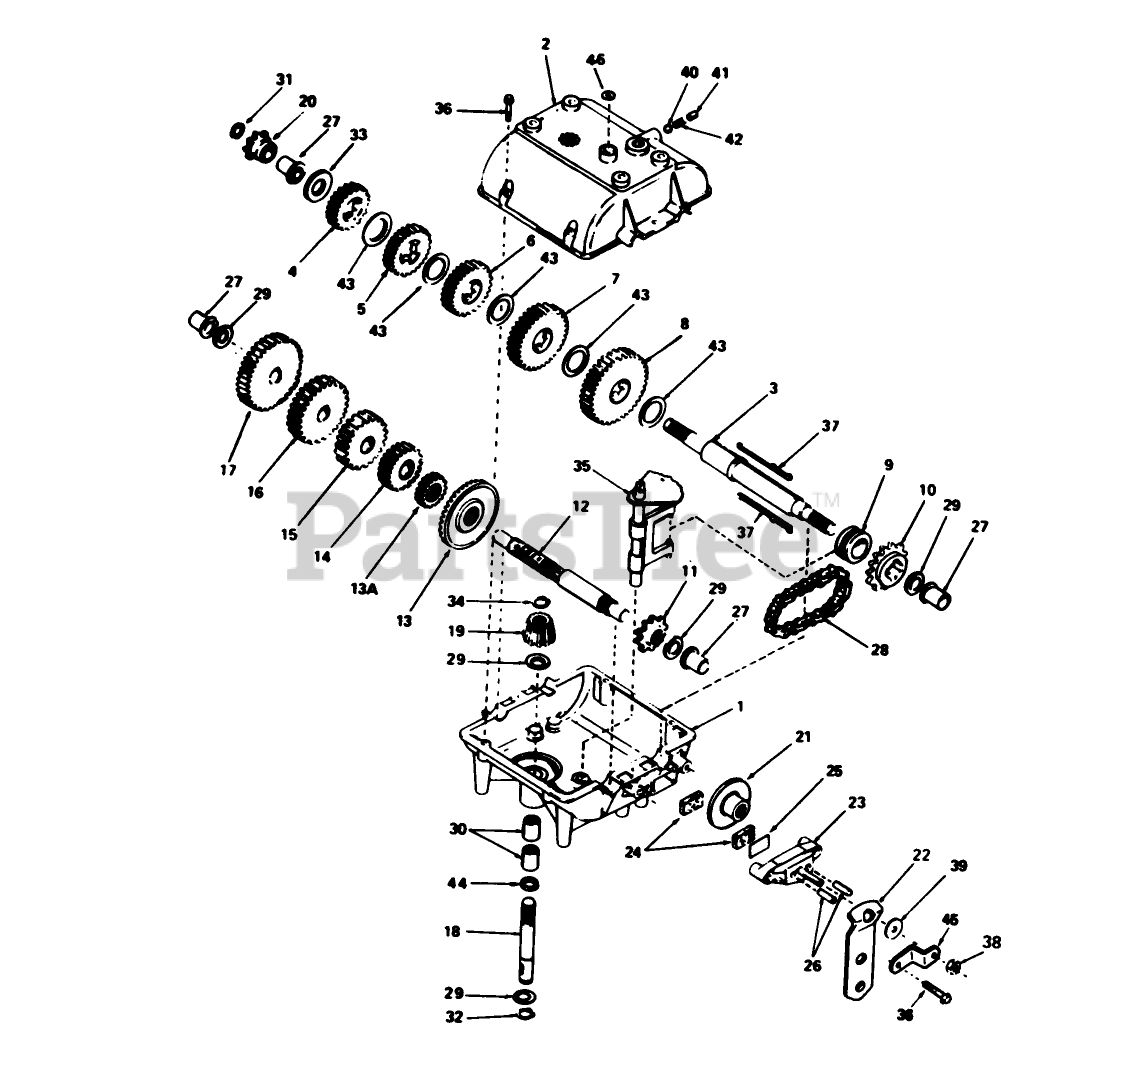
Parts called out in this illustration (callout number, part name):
1	Case-Transmission
2	Cover-Transmission
3	Shaft-Output Brake
4	Gear-Spur 20 teeth
5	Gear-Spur (22 teeth)
6	Gear-Spur, 25 Teeth
7	Gear-Spur, 30 Teeth
8	Gear-Spur, 35 Teeth
9	Collar-Shift
10	Sprocket-18 Teeth
11	Sprocket-9 Teeth
12	Countershaft
13	Gear-Bevel (42Teeth)
13A	Gear-Spur 15 Teeth
14	Gear-Spur, 20 Teeth
15	Gear-Spur, 25 Teeth
16	Gear-Spur (28 teeth)
17	Gear-Spur (30 teeth)
18	Shaft-Input
19	Bevel Pinion-Input
20	Sprocket (8 teeth)
22	Lever-Brake
23	Nozzle-Carburetor
24	Brake Pad
25	Brake Pad Plate
26	Dowel Pin
27	Bushing-Flange
28	Chain-Roller #41
29	Washer
30	Bearing-Needle
31	Piston Asm (.020 O S)
32	Ring-Snap
33	Washer
34	Ring-Retainer
35	Rod and Fork ASM
36	Ring Set (.020 O S)
38	Locknut
39	Washer
40	Ball-Steel
41	Screw-Set
42	Spring
43	Washer
44	O Ring
45	Bracket
46	Cut Seal-Square
